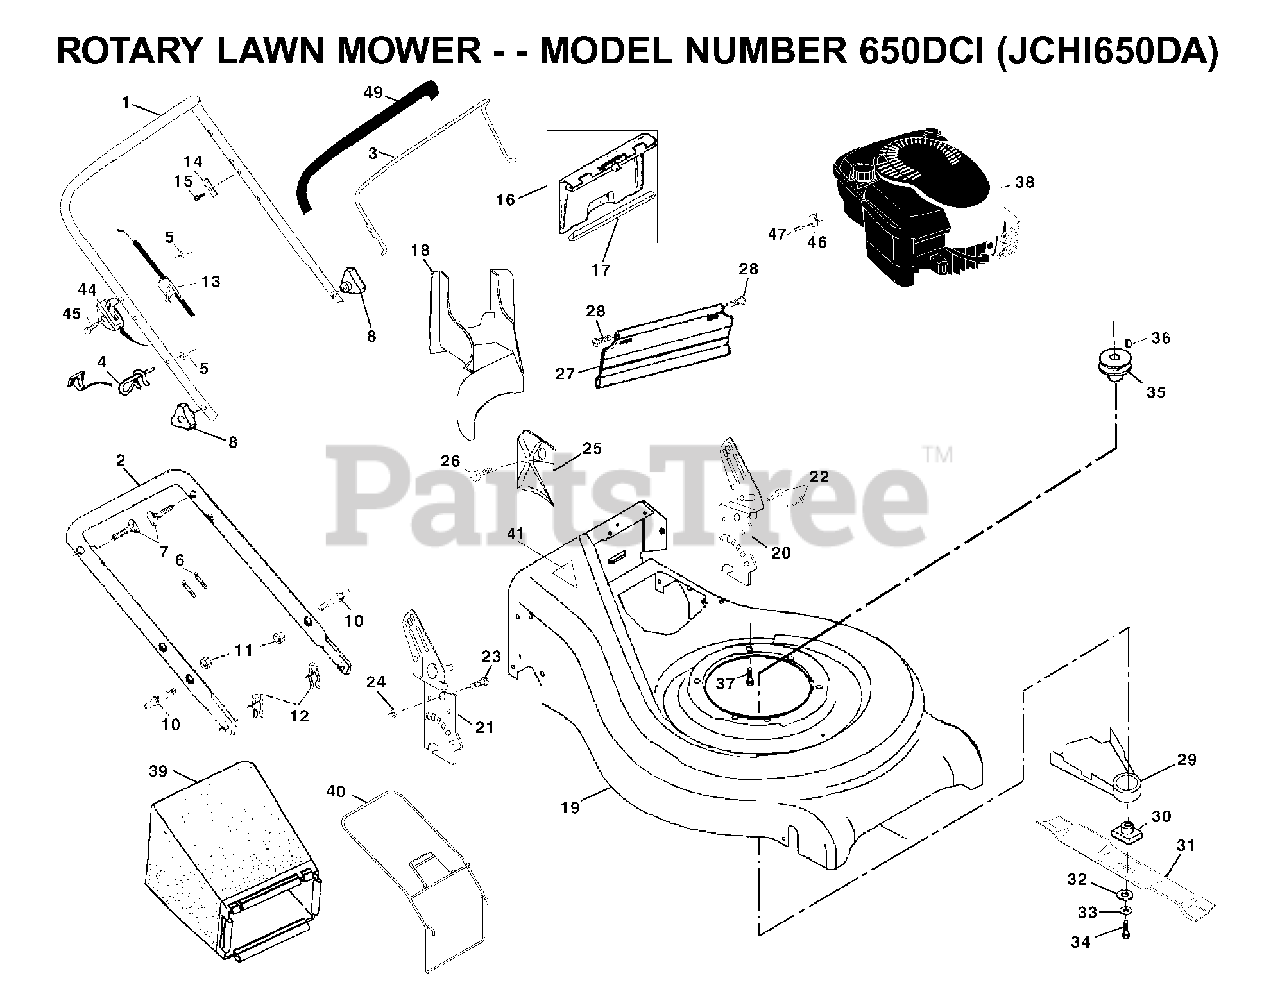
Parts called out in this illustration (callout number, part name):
2	HANDLE
3	CONTROL BAR
4	ROPE GUIDE
5	NUT
6	TIE GUIDE
7	HANDLE BOLT
10	BOLT
11	NUT
12	HAIRPIN COTTER
13	ENGINE ZONE CONTROL
14	BRACKET UPSTOP
15	SCREW.HEX.HEAD.WASHER.10-16
16	REAR DOOR KIT
17	SEALING
18	MULCH PLUG
20	.RACKET
22	SELF-TAPPING SCREW 5/16-18X3/4
23	BOLT, HEX HEAD 5/16-18
25	CLIPPING DEFLECTOR
27	REAR SKIRT
28	HINGE SCREW
29	DEBRIS SHIELD
30	RP BLADE ADAPTOR
31	21" MULCH BLADE PREMIUM
32	WASHER,HARDEN
33	LOCKWASHER
34	SCREW, HEX HD 3/8-24 X 1-3/8
35	ENGINE.PULLEY.FWG
36	HI PRO KEY PM
37	BOLT 3/8-16X1-1/8
40	GRASS CATCHER FRAME
41	DECAL NLA
44	THROTTLE TRIGGER
45	SCREW 1/4-20 X 2.12
46	CABLE CLAMP(ENGINE)
47	SCREW.HEX.HEAD.WASHER.10-16
49	GRIP.HANDLE.FOAM
